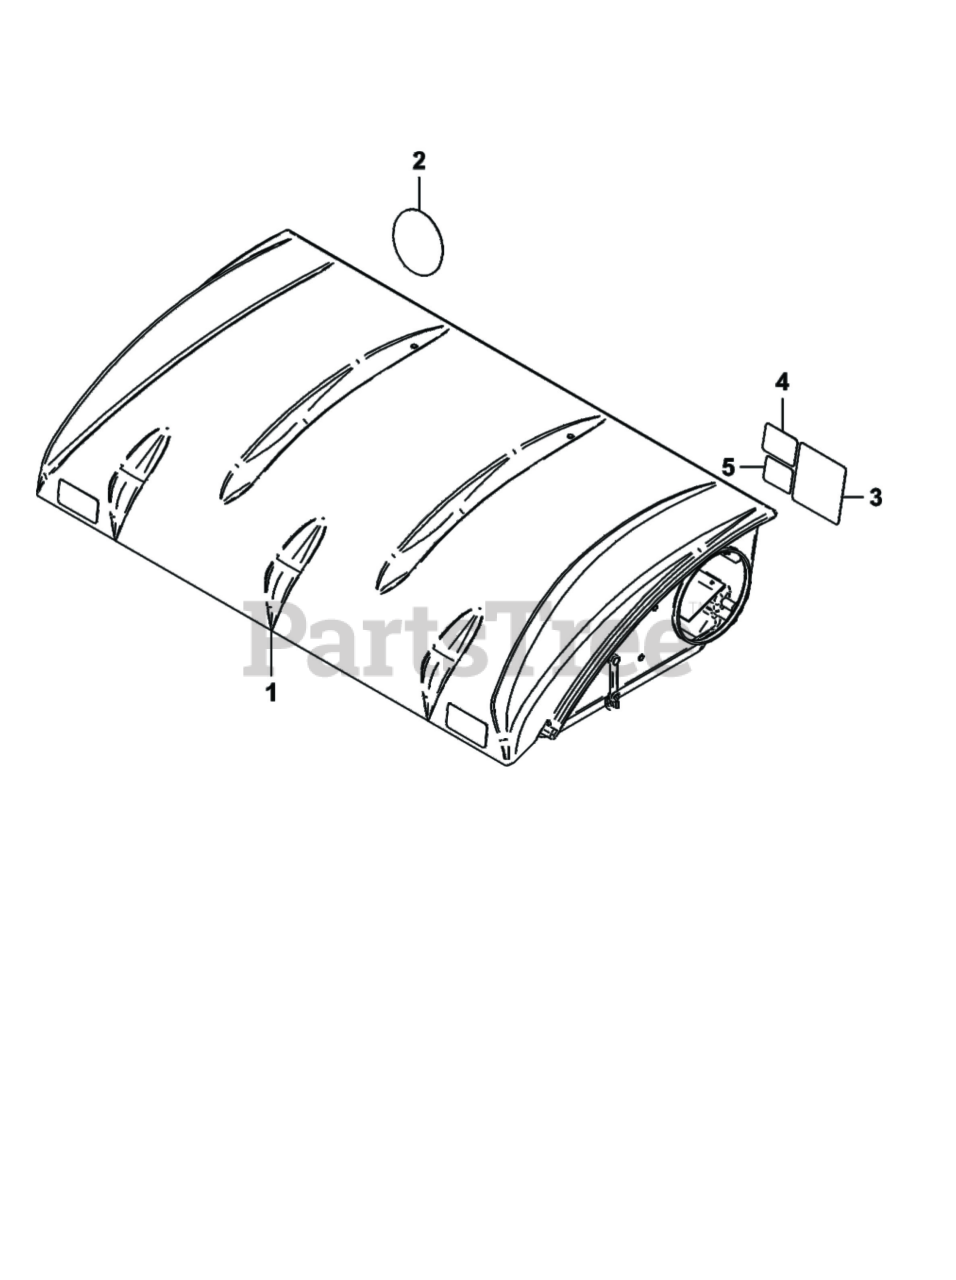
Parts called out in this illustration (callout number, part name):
1	TOP ASSEMBLY W/C LOGO
1	TOP ASSY-P3B-STD MODEL
2	BUILT IN USA LABEL
3	LABEL-WARNING
4	DECAL-TUBE WEAR
5	DECAL-WARNING
